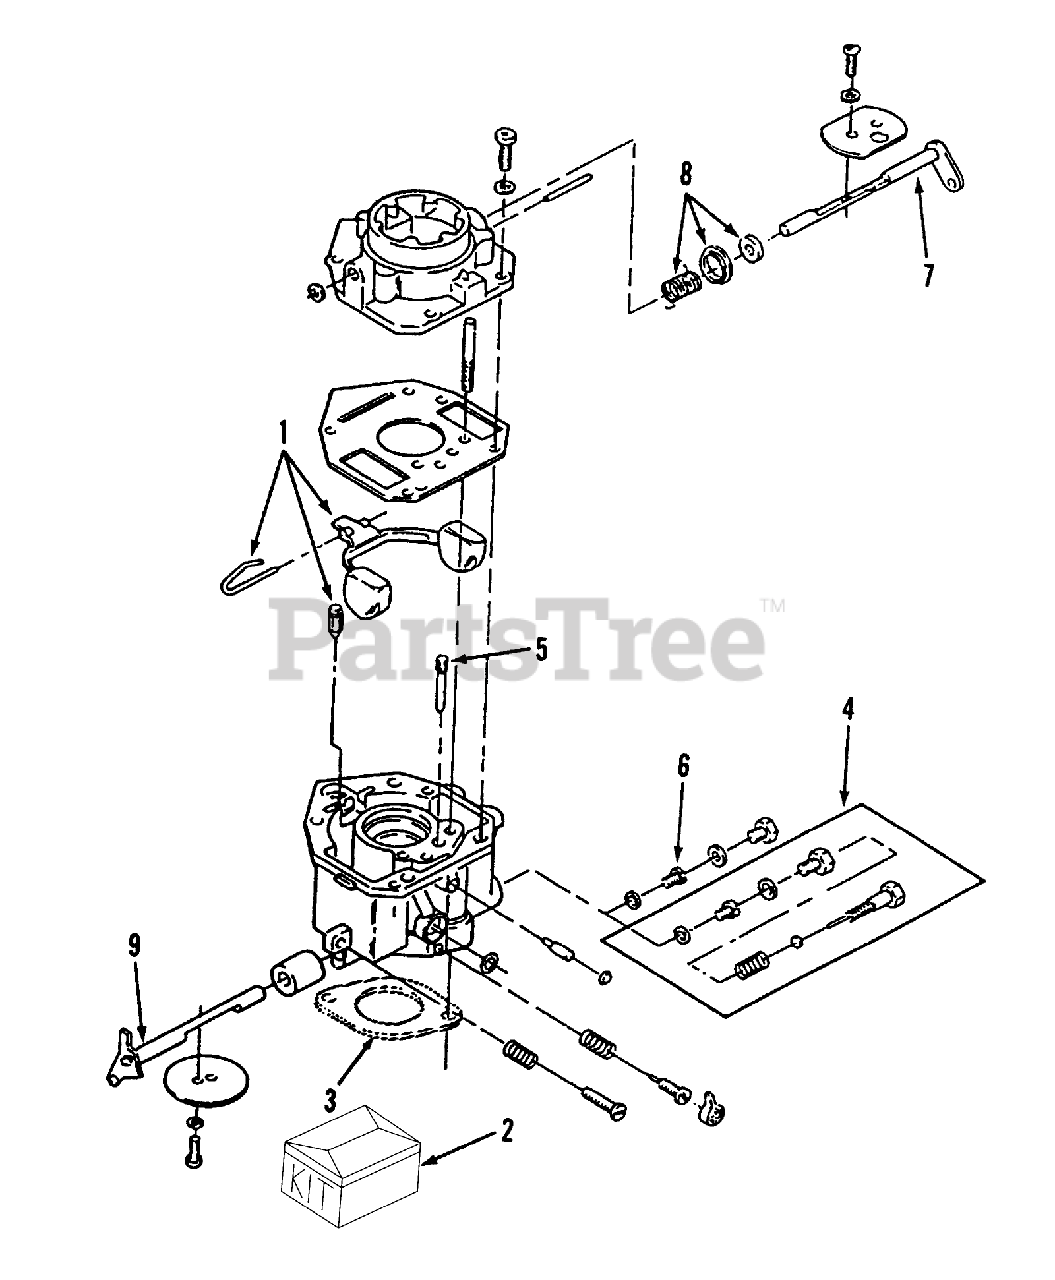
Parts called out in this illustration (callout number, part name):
2	REPAIR KIT
4	FIXED-JET
5	IDLE-JET
